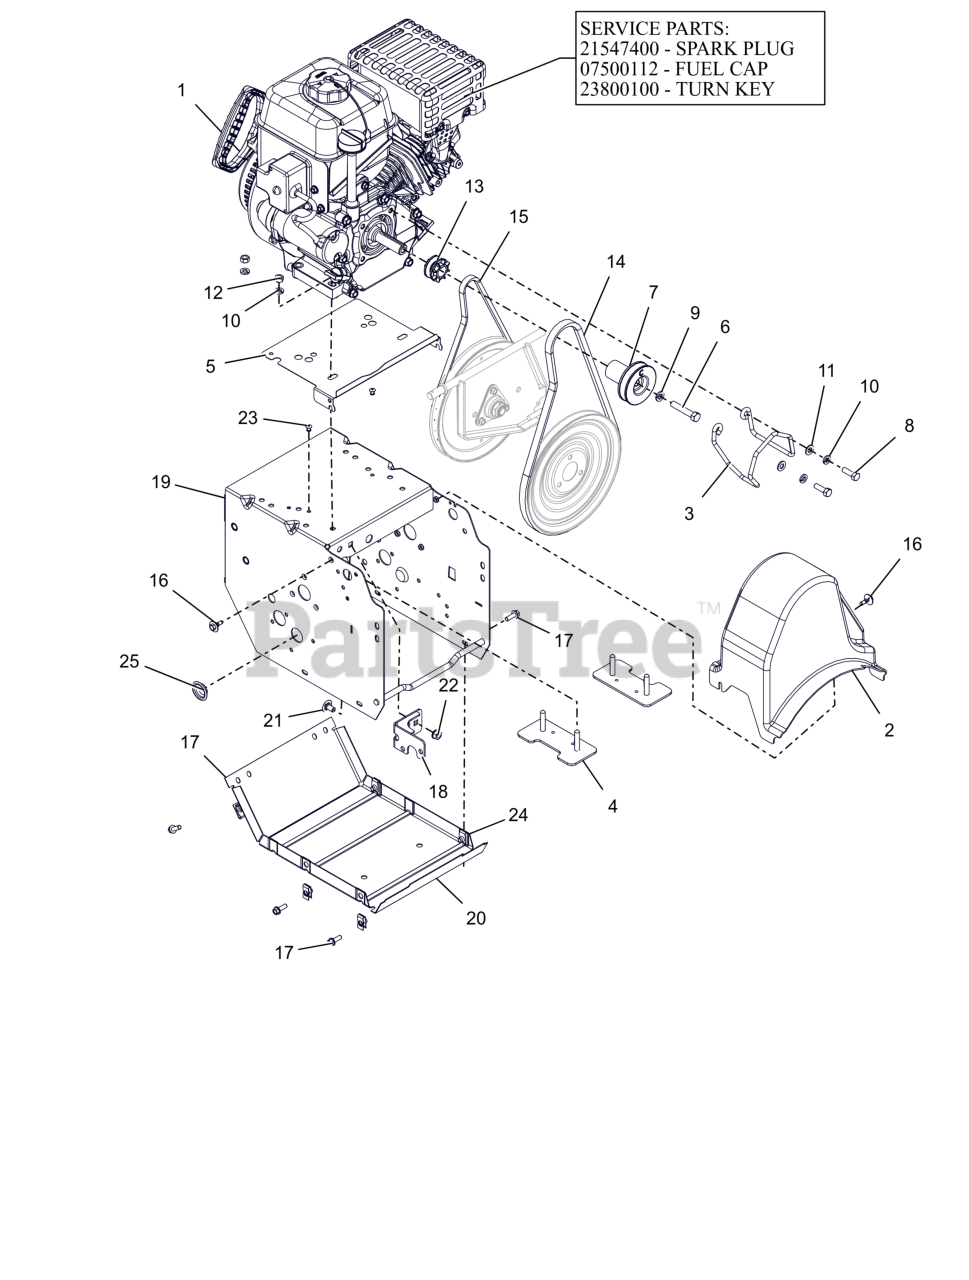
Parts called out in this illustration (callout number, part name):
1	ENGINE, AX223 GEN 2 120V
1	PLUG, SPARK
1	CAP, FUEL TANK (BLACK)
1	KEY, TURN LCT (RED/2 PACK)
2	COVER, COMPACT BELT
3	FINGER, BELT
4	STRAP, ENGINE BOLT-WELDMENT
5	BAFFLE, COMPACT
6	BLT, HEX .38-24X2.00 G5 ZCC
7	SHEAVE, ATTACHMENT SINGLE GRV
8	BLT, HEX 0.3125-24X1 G5 ZCC
9	WSHR,LK-REG .375X.094 ZCC
10	WSHR, LK-HVY .312X.097 ZCC
11	WSHR,FLT .344X.688X.065 ZCC
12	NUT, HEX .312-18 ZCC
13	SHEAVE, TRACTION
14	V-BELT, HA-RAW EDGE
15	V-BELT, 3L-WRAPPED
16	SCR-TAP .25-20X.5 CAPTIVE
17	BLT, HWH .25-20X.75 G5 ZCC
18	WELDMENT, FRAME BRACKET
19	FRAME, MAIN
20	COVER, BOTTOM
21	BLT, RHSSN .31-18X.625 G5 ZCC
22	NUT-LK-TOP-FLG .312-18 GF ZCC
23	RVT, POP .1875 ZCC
24	NUT-RTNR .25-20X.56
25	PLUG, HOLE - 1.00" FLEXTEMP
